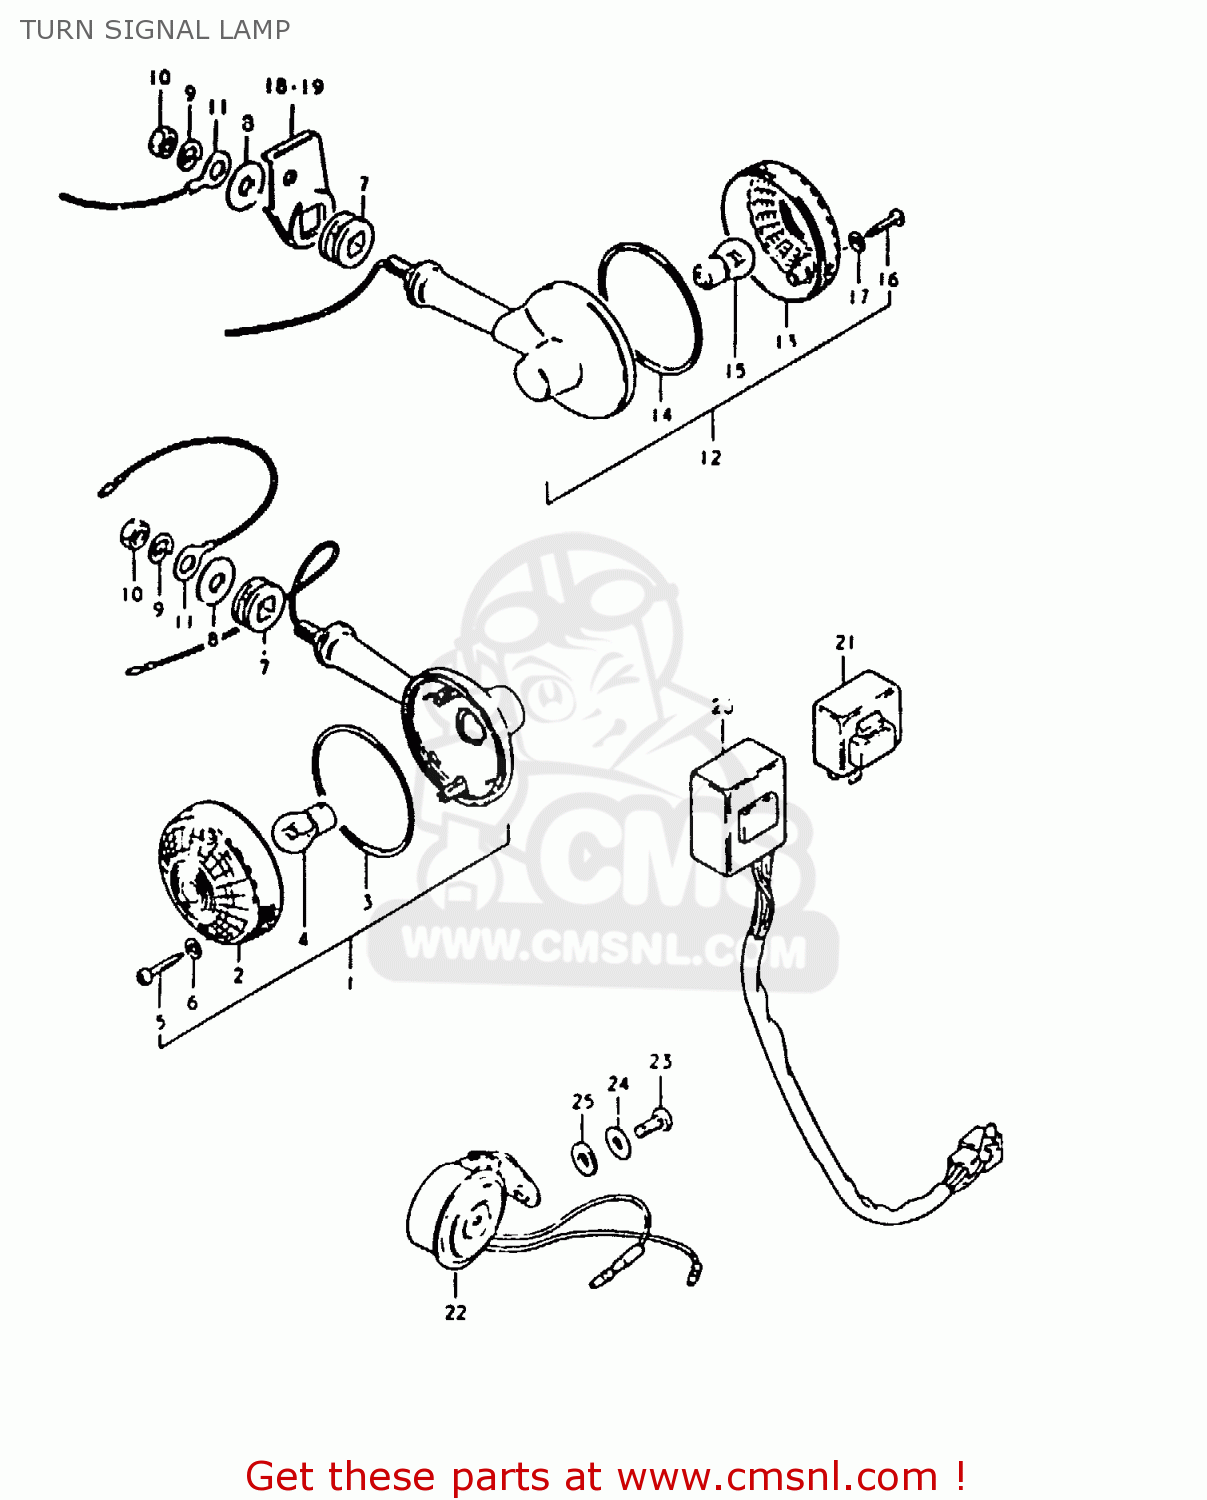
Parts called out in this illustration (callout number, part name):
1	LAMP ASSEMBLY,FRONT TURN SIGNAL
2	LENS
3	GASKET (NAS)
4	BULB(12V23W,STANLEY,A4577A)
5	BOLT
6	GASKET (NAS)
7	CUSHION
8	WASHER
9	LOCK WASHER
10	NUT
11	LEAD WIRE,EARTH
12	LAMP ASSEMBLY,FRONT TURN SIGNAL
13	LENS
14	GASKET (NAS)
15	BULB(12V23W,STANLEY,A4577A)
16	BOLT
17	GASKET (NAS)
18	BRACKET,RR TURNSIGNAL LAMP,R
19	BRACKET,RR TURNSIGNAL LAMP,L
20	UNIT,TURN SIGNAL CONTROL
21	RELAY,TURN SIGNAL
22	BUZZER ASSEMBLY,TURN SIGNAL
23	SCREW
24	WASHER
25	WASHER(6X13X2)
